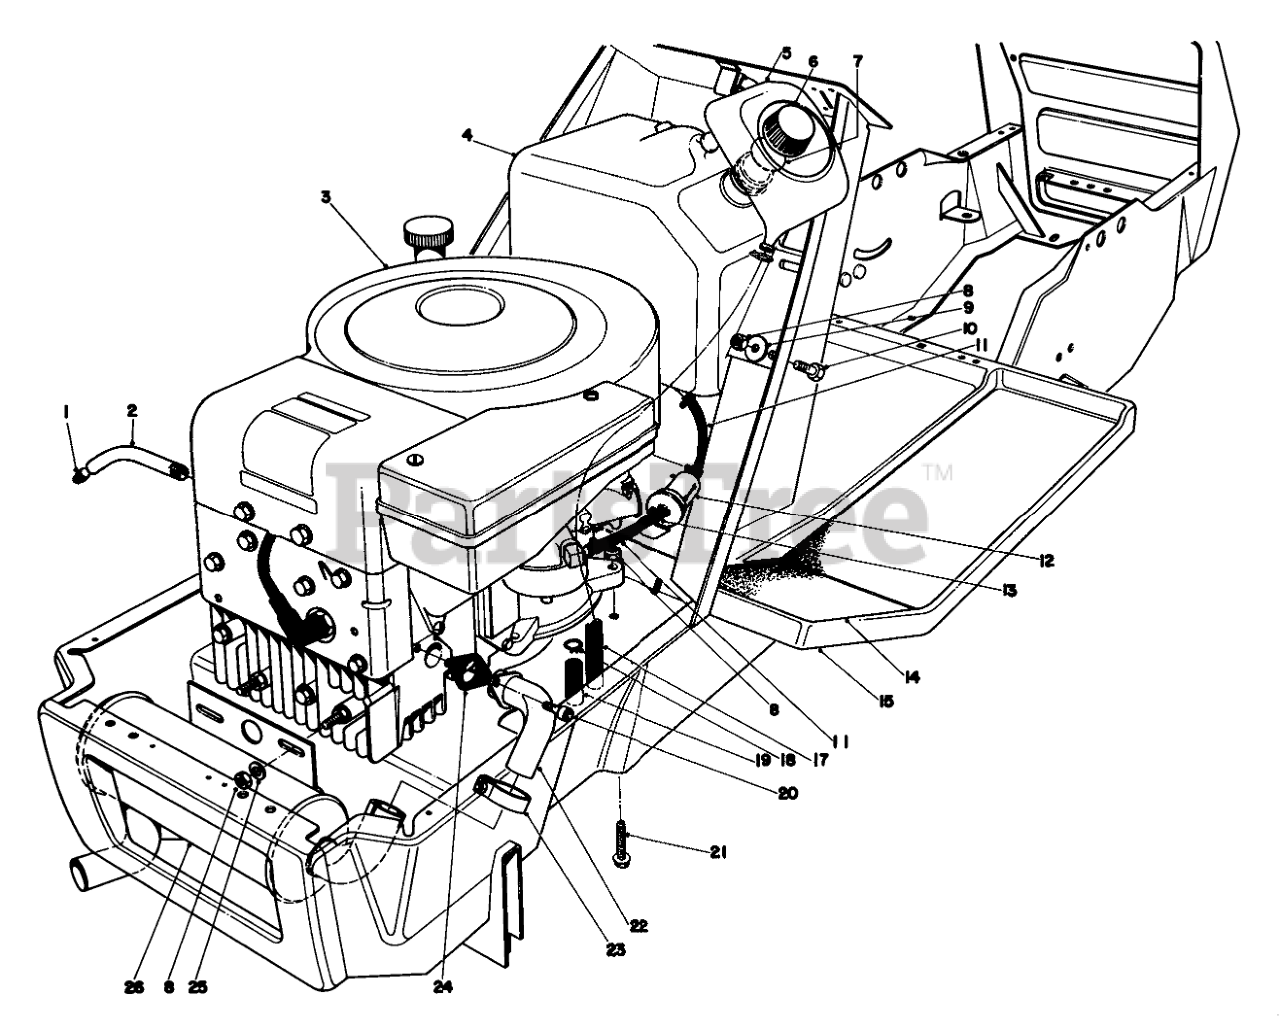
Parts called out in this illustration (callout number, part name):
1	PLUG-PIPE, SQH
2	OIL DRAIN TUBE
3	Engine
4	Gas Tank (Incl. Ref. #5)
5	Funnel-Overflow
6	Gas Cap (Incl. Ref. #7)
7	Gasket Gas Cap
8	NUT-LOCK, CONE
9	WASHER
10	SCREW-HH
11	GAS HOSE
12	FUEL FILTER
13	CLAMP-HOSE
14	LH FOOT TREAD
15	Frame
17	FUNNEL HOSE
18	HOSE CLAMP
19	CARB DRAIN HOSE
20	SCREW-HSH
21	SCREW-HH
22	Exhaust Pipe
23	MUFFLER CLAMP
24	Exhaust Gasket
25	WASHER-PLAIN
26	MUFFLER
